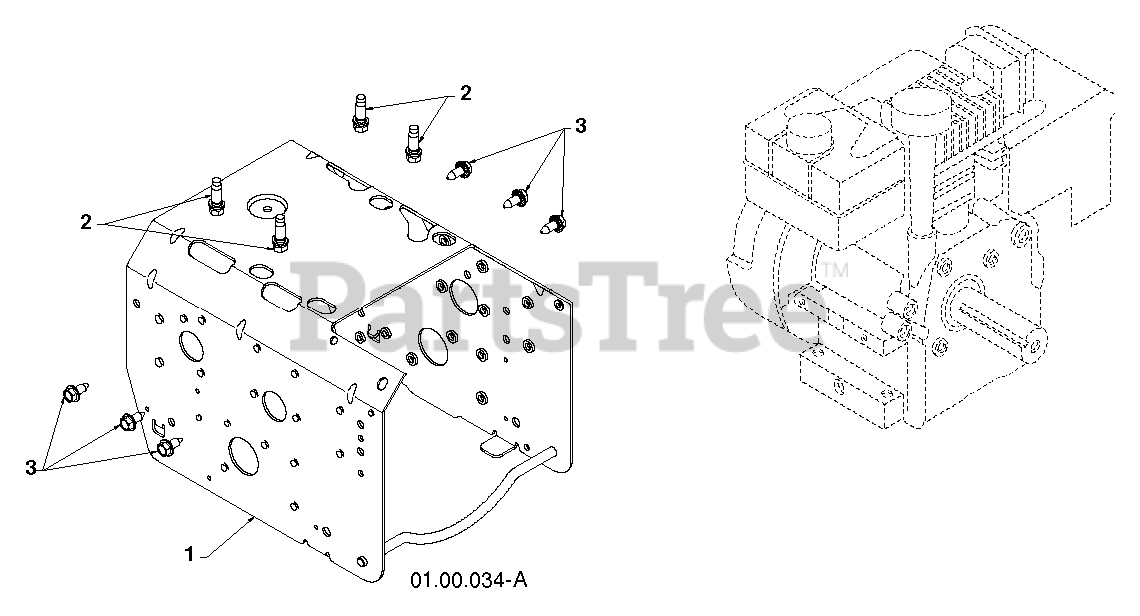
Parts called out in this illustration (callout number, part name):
1	FRAME.WELD.PNT.CHAIN.ORANGE
2	BOLT 3/8-16X1-1/8
3	BOLT.HEX.HD.WASHER.5/16-18X.75
